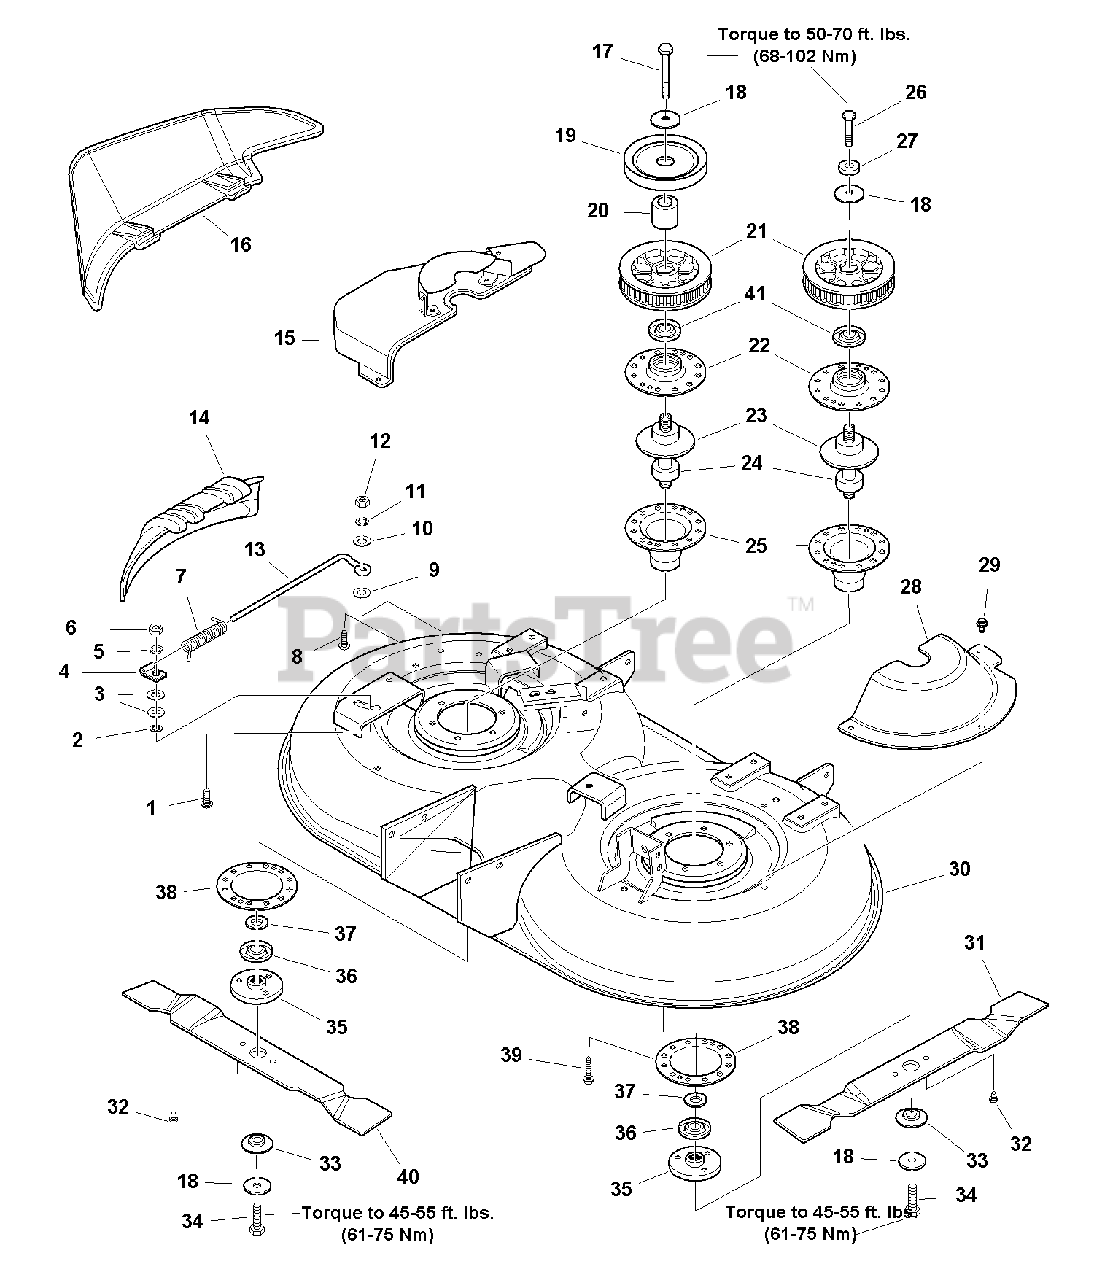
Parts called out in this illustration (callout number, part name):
1	CARRIAGE BOLT,1/4-20 x 7/8, Black
2	NUT, Push, 1/4, Black
3	WASHER, 1/4, Black
4	CLAMP, Wire, Black
5	LOCKWASHER, 1/4, Black
6	NUT, Hex, 1/4-10, Black
7	SPRING, Torsion, Black
8	CARRIAGE BOLT, 5/16-18 x 1, Black
9	NUT, Push, 5/16, Black
10	WASHER, 5/16, Black
11	LOCKWASHER, 5/16, Black
12	NUT, Hex, 5/16, Black
14	DOOR, Mulching
15	COVER ASSEMBLY, RH
16	DEFLECTOR, Discharge
17	CAPSCREW, Hex Head, 7/16-14 x 4-1/2, GR8, Black
18	WASHER, Spring, 7/16, Black
19	PULLEY, 5" OD x 1" ID
21	SPROCKET & FLANGE ASSEMBLY
22	HOUSING, Arbor, Top
23	GASKET, Foam
24	ARBOR SHAFT & BEARINGS ASSEMBLY
25	HOUSING, Arbor, Bottom, w/Lube Fitting
26	CAPSCREW, Hex Head, 7/16-14 x 2-3/4, GR 8, Black
27	WASHER, 7/16, Black
28	COVER, Arbor, LH, Black
29	CAPSCREW, Hex Washer Head, Tap Tite, 5/16-18 x 1/2, Black
30	HOUSING ASSEMBLY
31	BLADE, Mower, 20-3/8, LH
33	WASHER, Spline
34	CAPSCREW, Hex Head, 7/16-14 x 1-1/4, GR 8
35	ADAPTER, Blade
36	SHIELD, Bearing
37	WASHER, Shim, Black
38	ADAPTER, Arbor
39	CAPSCREW, Hex Head, 5/16-18 x 1, Black
40	BLADE, Mower, 20-3/8, RH
41	SHIELD, Bearing Upper, Arbor
